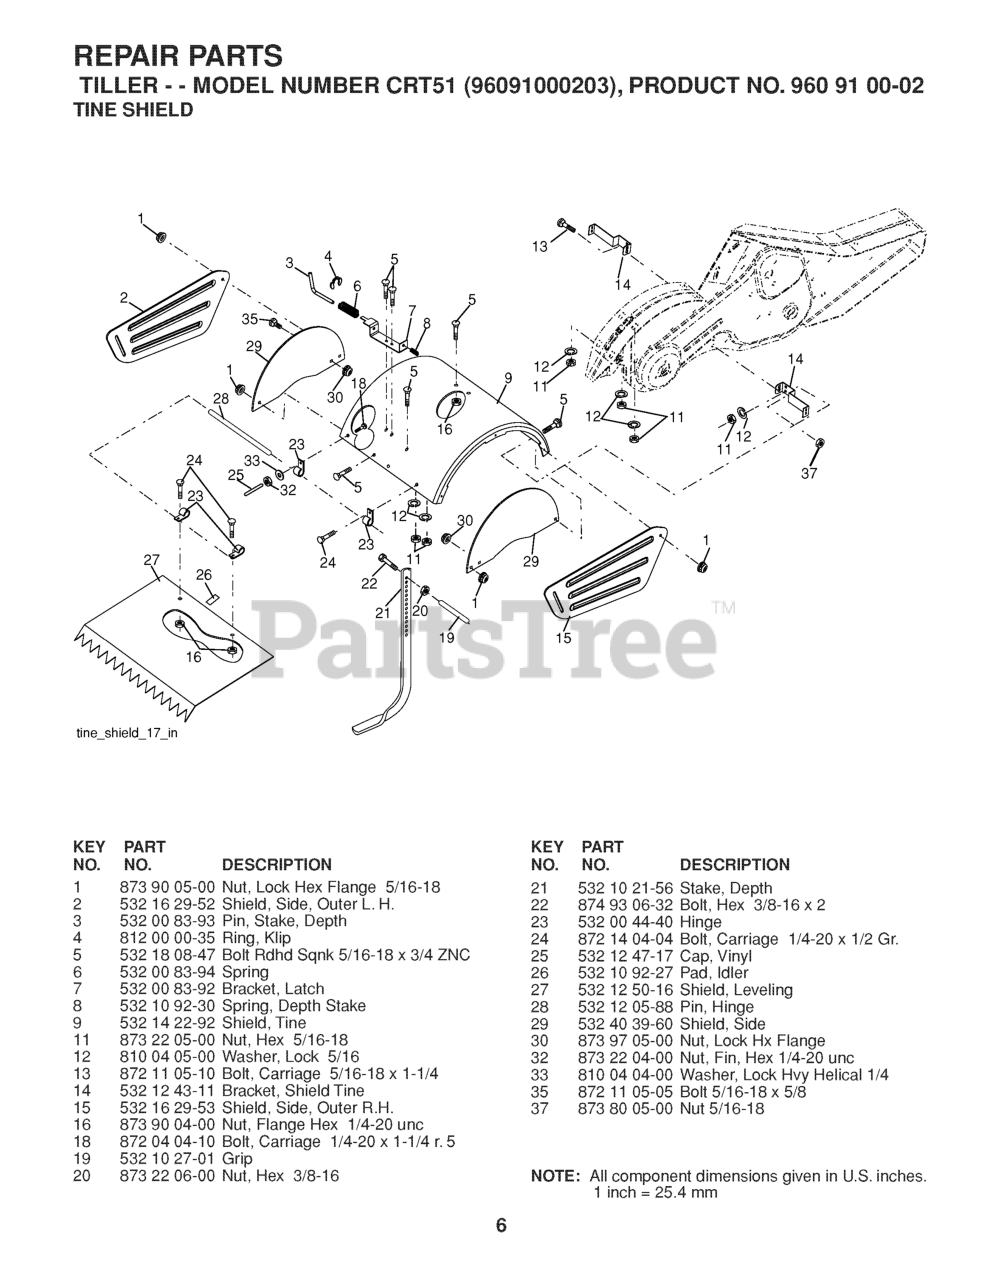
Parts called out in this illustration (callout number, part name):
1	NUT LOCK HEX FLANGE 5/16-18
2	SHIELD
3	STAKE PIN TI
4	RING, KLIP
5	BOLT, RDHD SQNK 5/16-18 X 3/4
7	BRACKET.LATCH.STAKE.3.20.BLACK
8	SPRING CRT
9	SHIELD
12	WASHER.LOCK.HVY.HLCL.SPR.5/16
13	BOLT.CARRIAGE.5/16-18
14	BRACKET.TINE.SHIELD.TILLER.BLA
15	SIDE SHIELD RH
16	NUT T
20	NUT.HEX.3/8-16UNC
21	STAKE.DEPTH.16.CRT.BLACK
22	BOLT.375-16
25	VINYL CAP TI
26	PAD IDLER TI
27	SHIELD LEVELING
28	PIN.HINGE.TILLER
29	SHIELD.ASM.SIDE.ORANGE.(OLD)
30	LOCKNUT-FLANGE 5/16-18
32	NUT
33	LOCKWASHER
35	BOLT.CARR.5/16-18X5/8.SHORT
37	NUT.71038.31-18.HEX.NYLOCK
